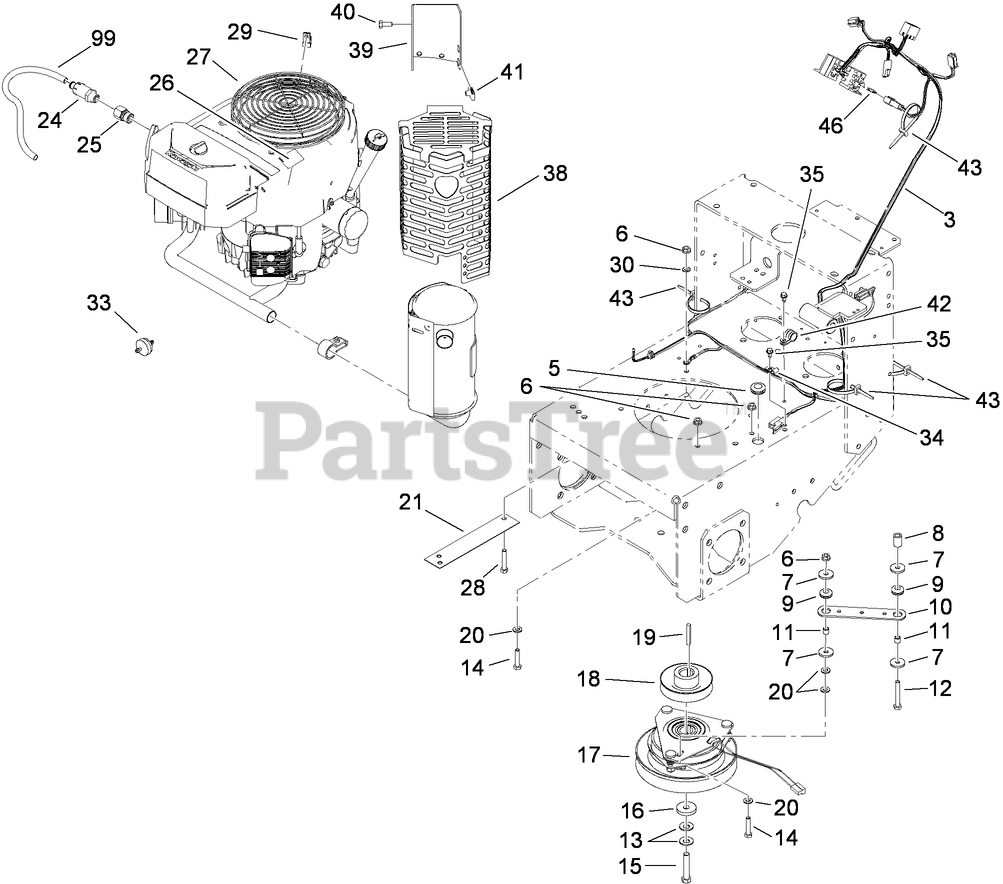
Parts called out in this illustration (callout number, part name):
3	HARNESS-WIRE
5	GROMMET
6	NUT-HF
7	WASHER
8	TUBE-RETAINER
9	GROMMET
10	STRAP-CLUTCH, BRAKE
11	SPACER
12	SCREW-HH
13	WASHER-SPRING
14	SCREW-HH
15	SCREW-HH
16	WASHER
17	CLUTCH / BRAKE ASM
18	Pulley
19	KEY-SQUARE
20	WASHER-PLAIN
21	COVER-PULLEY
24	VALVE-DRAIN, OIL
25	Adapter
26	DECAL-WARNING
28	SCREW-HH
29	CLAMP-CABLE
30	WASHER-LOCK
33	FILTER-FUEL
34	CLIP-CLOSED, INSULATED
35	SCREW
38	MUFFLER SHIELD ASM
39	BRACKET-MUFFLER
40	SCREW-HH
41	NUT-U
42	CLAMP-R
43	TIE-CABLE
46	FUSE-BLADE, 10 AMP
99	HOSE-DRAIN, OIL
